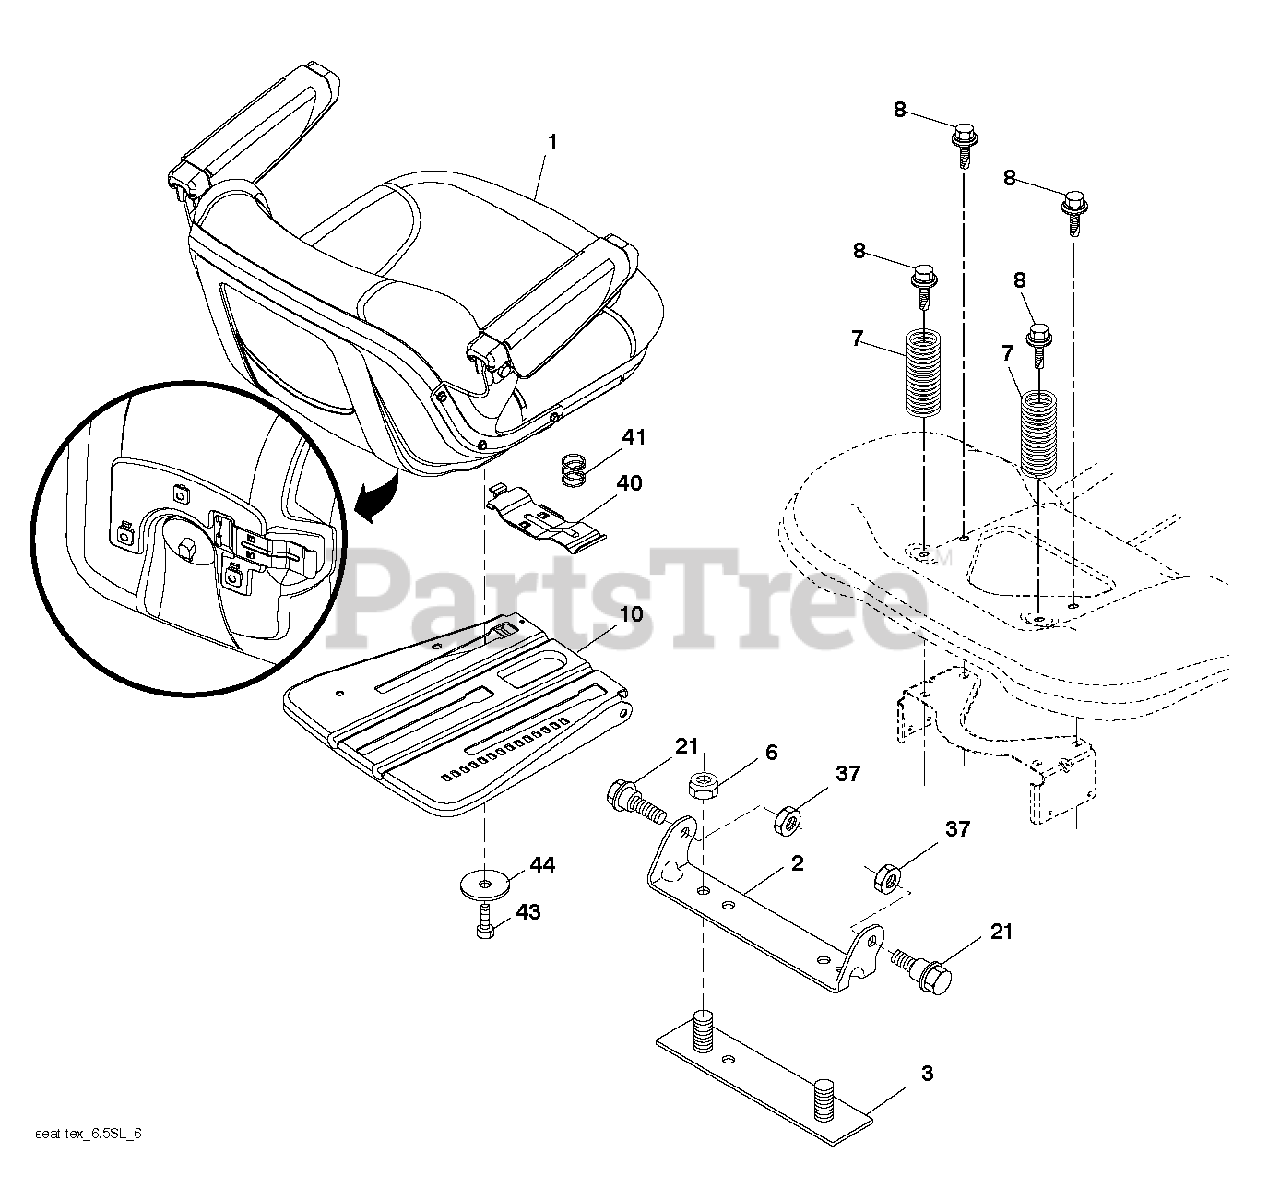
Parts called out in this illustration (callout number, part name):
1	SEAT.TH154.GREY.HUS.ARMREST
2	BRKT.PIVOT.FENDER
3	STRAP
6	NUT
7	SPRING.COMPRESSION.SEAT.BLACK
8	BOLT, 5/16-18 X 1 3/4
10	PAN.ASM.SEAT.3PT
21	BOLT.5/16-18X5/8.SHOULDER
37	NUT.71038.31-18.HEX.NYLOCK
40	HANDLE.SLIDE.SEAT.TEX.GREY
41	SPRING.LATCH.SEAT.TEX
44	WASHER 13/32 X 2-3/8 X 12GA
